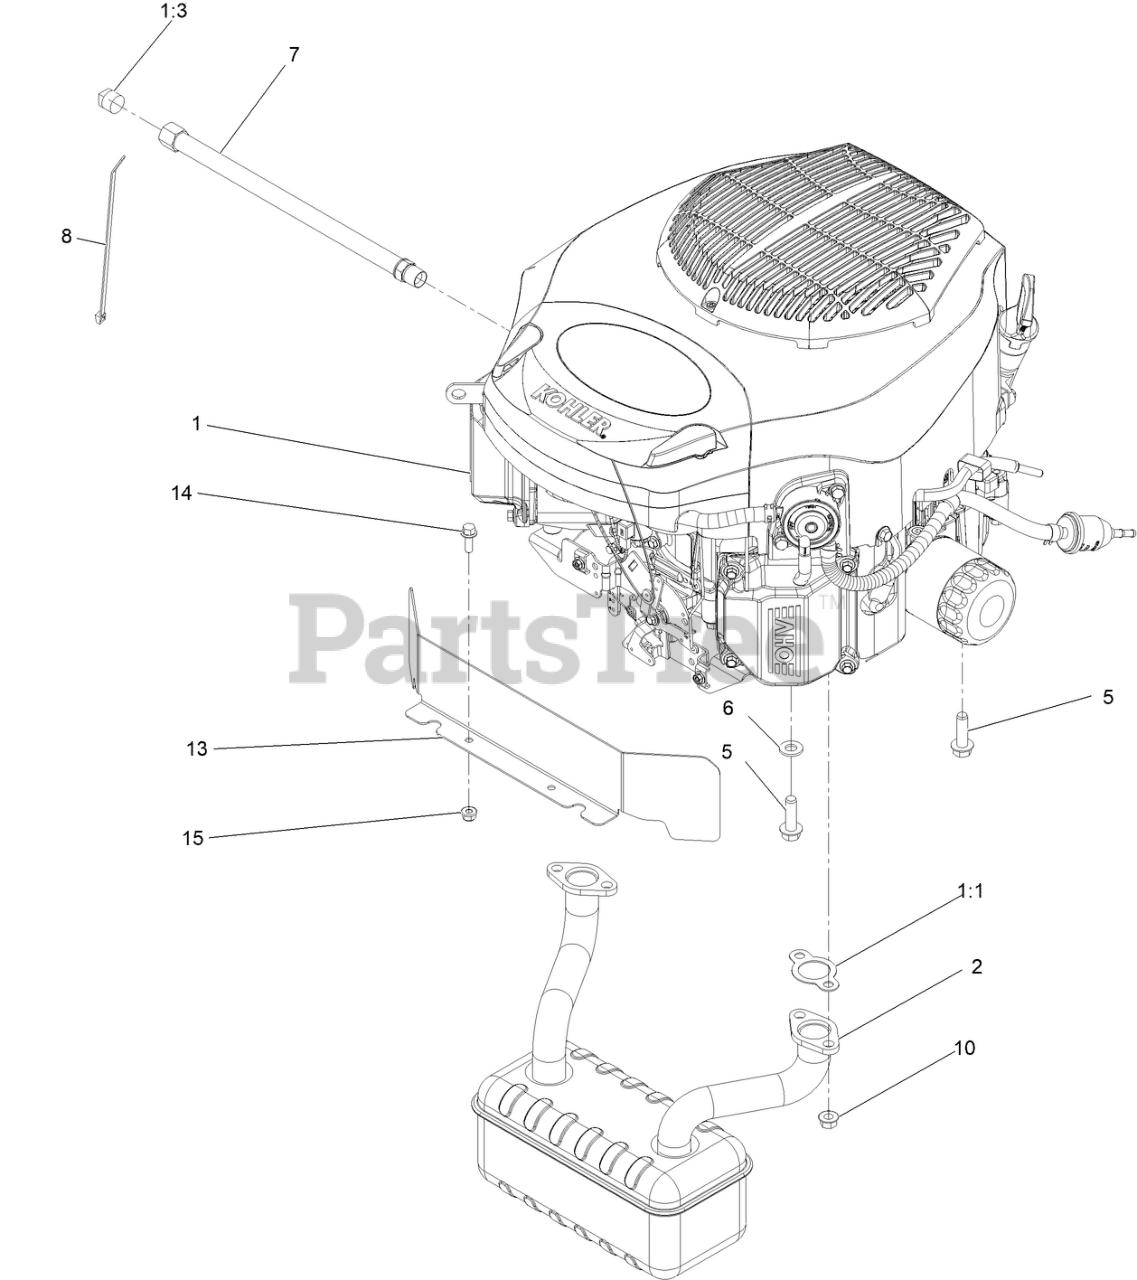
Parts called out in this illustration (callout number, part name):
1:1	GASKET-EXHAUST
1:3	PLUG-PIPE, SQH
2	Muffler
5	SCREW-THD
6	WASHER-FLAT
7	HOSE-DRAIN, OIL
8	TIE-CABLE
13	SHIELD-HEAT
14	Screw-HHF
15	SCREW-SHOULDER
